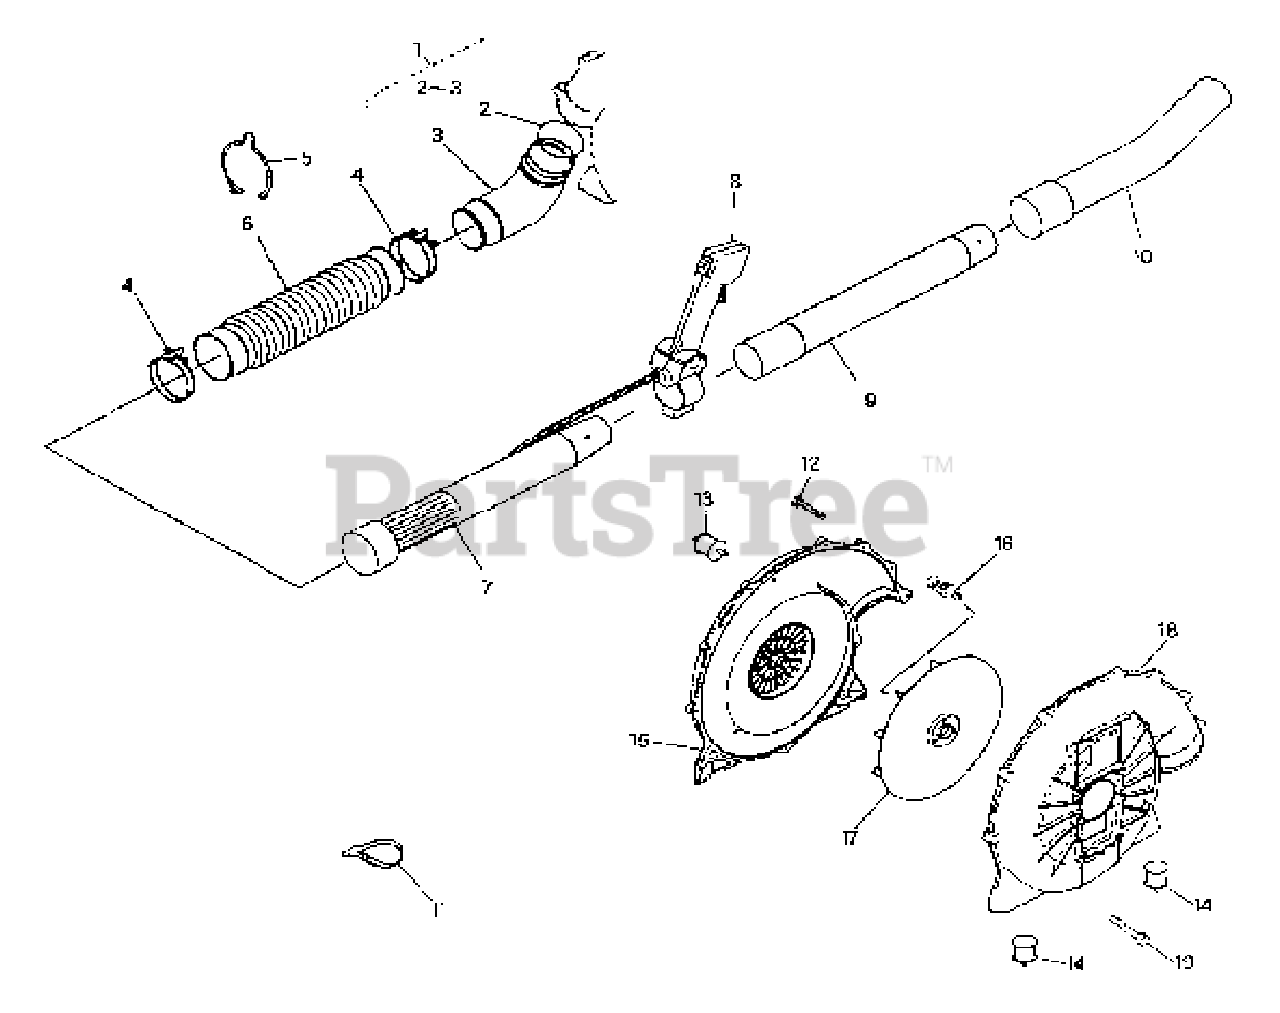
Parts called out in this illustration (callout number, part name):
1	Elbow Pipe
2	O-Ring
3	Elbow Pipe
4	Hose Band
5	Wire Clamp
6	Flex Pipe
7	Base Pipe
8	Throttle Assy.
9	Middle Pipe
10	Bend Pipe
11	Wire Band
12	Tapping Screw
13	Isolating Rubber
14	Isolating Rubber
16	Lock Bolt
19	Lock Bolt
